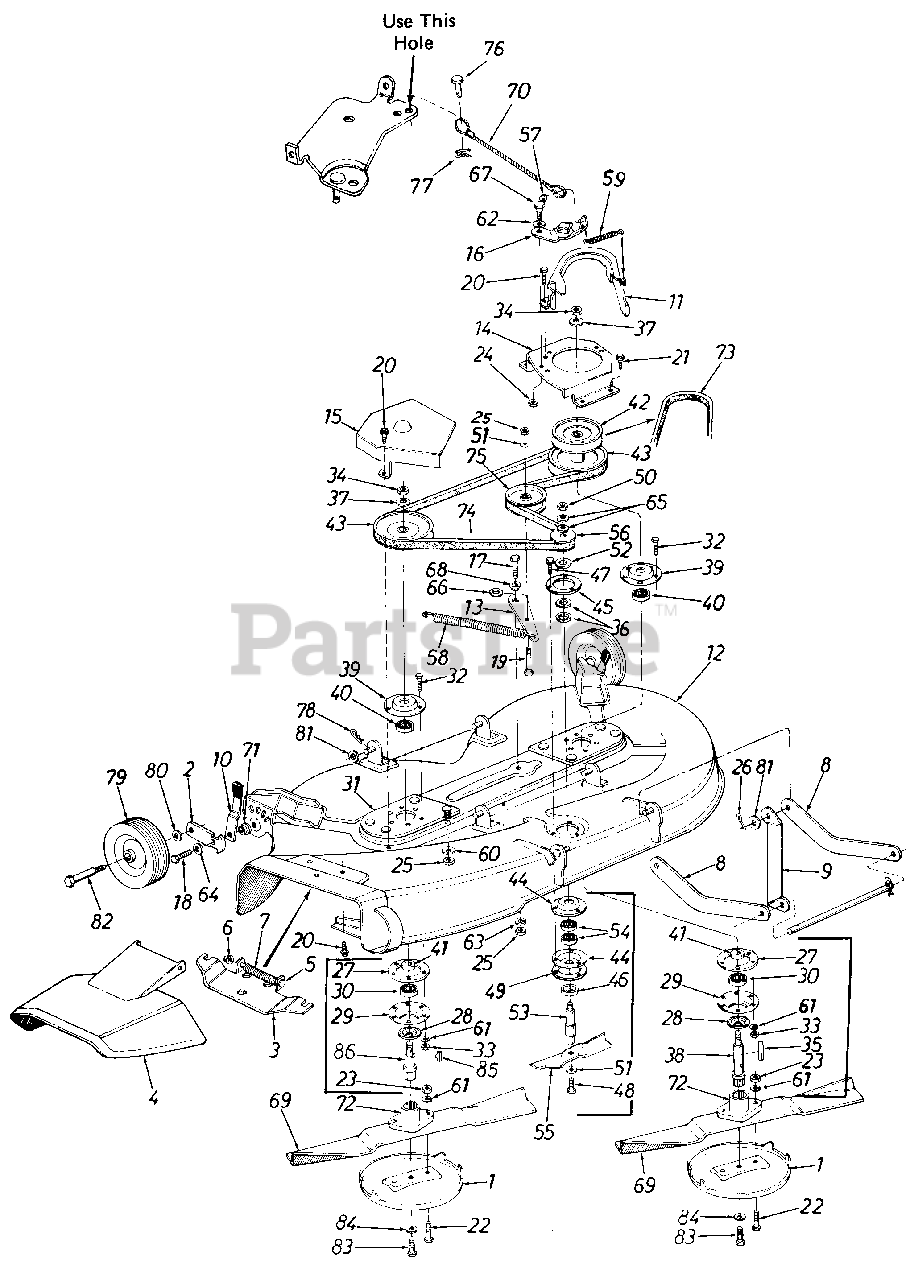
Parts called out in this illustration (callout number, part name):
1	Anti-Scalp Plate
2	Wheel Pivot Bar
3	Adapter
4	Chute Cover Ass'y.
5	Hinge Pin
6	Cap Speed Nut 1/4" Rod.
7	Torsion Spring
11	Belt Guard
12	44" Deck Ass'y.
13	Idler Bracket
14	Pulley Cover L.H.
17	Hex Bolt 3/8-24 x 1.00"
18	Hex Bolt 3/8-24 x 1.25" Lg.
19	Hex Bolt 3/8-24 x 1.50"
20	Hex Wash. S-Tapp Scr. 1/4-20 x .50"
21	Hex Wash. Hd. Tapp Scr. 5/16-18 x .75" Lg.
22	Hex Bolt 5/16-24 x 1.25" (Grade 5)
23	Hex Nut 5/16-24 Thd.
24	Hex Cent. L.-Nut 5/16-18 Thd.
25	Hex Nut 3/8-24 Thd.
26	Cotter Pin 3/32 Dia. x 1.00" Lg.
27	Reinforcement Plate
28	Bearing Shield
29	Open Brg. Housing 1.85 I.D.
30	Ball Brg. .787 I.D. x 1.85 O.D. x .551
31	Spindle Mounting Plate Ass'y.
32	Hex Bolt 5/16-24 x 1.0"Lg.
33	Hex Nut-5/16-24
34	Hex Jam Nut 5/8-18 Thd.
35	Square Key 3/16 x 2.25" Lg.
36	Fl. Wash. 5/8" I.D. x 15/16" O.D
37	Bell. Wash. .630 I.D. x 1.25 x .090
38	44" Deck Blade Spindle
39	Bearing Housing 1.85 I.D.
40	Ball. Brg. .787 I.D. x 1.85 O.D. x .551
41	Spacer 1.0 O.D. x .790 I.D. .350 Lg.
42	5/8 "V"-Pulley . 79 I.D. x 5.75 O.D.
43	"V"-Pulley .79 I.D. x 6.50 0.D.
44	1-3/8" I.D.-Bearing Housing
45	Reinforcement Plate
46	Bearing Shield
47	Hex "B" Tap Scr. .250" x 1.0" Lg.
48	Hex Cl.-Scr. 3/8-24 x .88Lg.
49	Reinforcement Plate
50	Hex Jam Nut 1/2-20 Thd.
51	Bell.-Wash. .400 I.D. x .88 O.D. x .060
52	Fl.-Wash. .635 x 1.04 O.D. x .120"
53	6.5" Blade Spindle
54	Ball Brg. .62 I.D. x 1.30" O.D. x .44 "
55	6.50" Blade
56	1/2" V Pulley Half .625 I.D. x 2.25" O.D.
57	Cap Speed Nut 1/4" Rod.
58	Extension Spring .73 O.D. x 4.31 Lg.
59	Extension Spring .38 x 2.75" Lg.
60	Bell.-Wash. .400 I.D. x .88 O.D. x .060
61	L.-Wash. 5/16" I.D.
62	Spring Wash. .445 I.D. x .75 O.D. x .017
64	Bell.-Wash. .400 I.D. x 1.13 O.D. x .030
65	Bell.-Wash. .505 I.D. x 1.00 O.D. x .075
66	Spring Wash. .650 I.D. x .875 O.D. x .015 Thk.
67	Shld. Bolt.437 Dia. x .180
68	Shld. Spacer.625 I.D.
69	Mower Blade 21.88
70	Brake Cable Ass y.
71	Shld. Spacer
72	Blade Adapter
73	"V"-Belt 1/2 x 56" Lg.
74	"V"-Belt 1/2 x 74"Lg.
75	Fl.-Idler w/Flanges 3.50 O.D.
76	Clevis Pin 1/4 Dia. x .53Lg.
77	Intern. Cotter Pin 5/16" Dia.
78	Intern. Cotter Pin 1/2" Dia.
79	Deck Wheel 6.0 x 1.38
80	Bell.-Wash. .400 I.D. x .88 O.D. x .060
81	Fl.-Wash. .531 I.D. x .93 O.D. x .090
82	Shoulder Bolt 3/8-16 x 1.41
83	Hex Bolt 3/8-24 x .88" Lg.
84	L.-Washer 3/8 I.D.
85	Sq. Key 3/16 x .75" Lg.
86	44" Deck Blade Spindle
